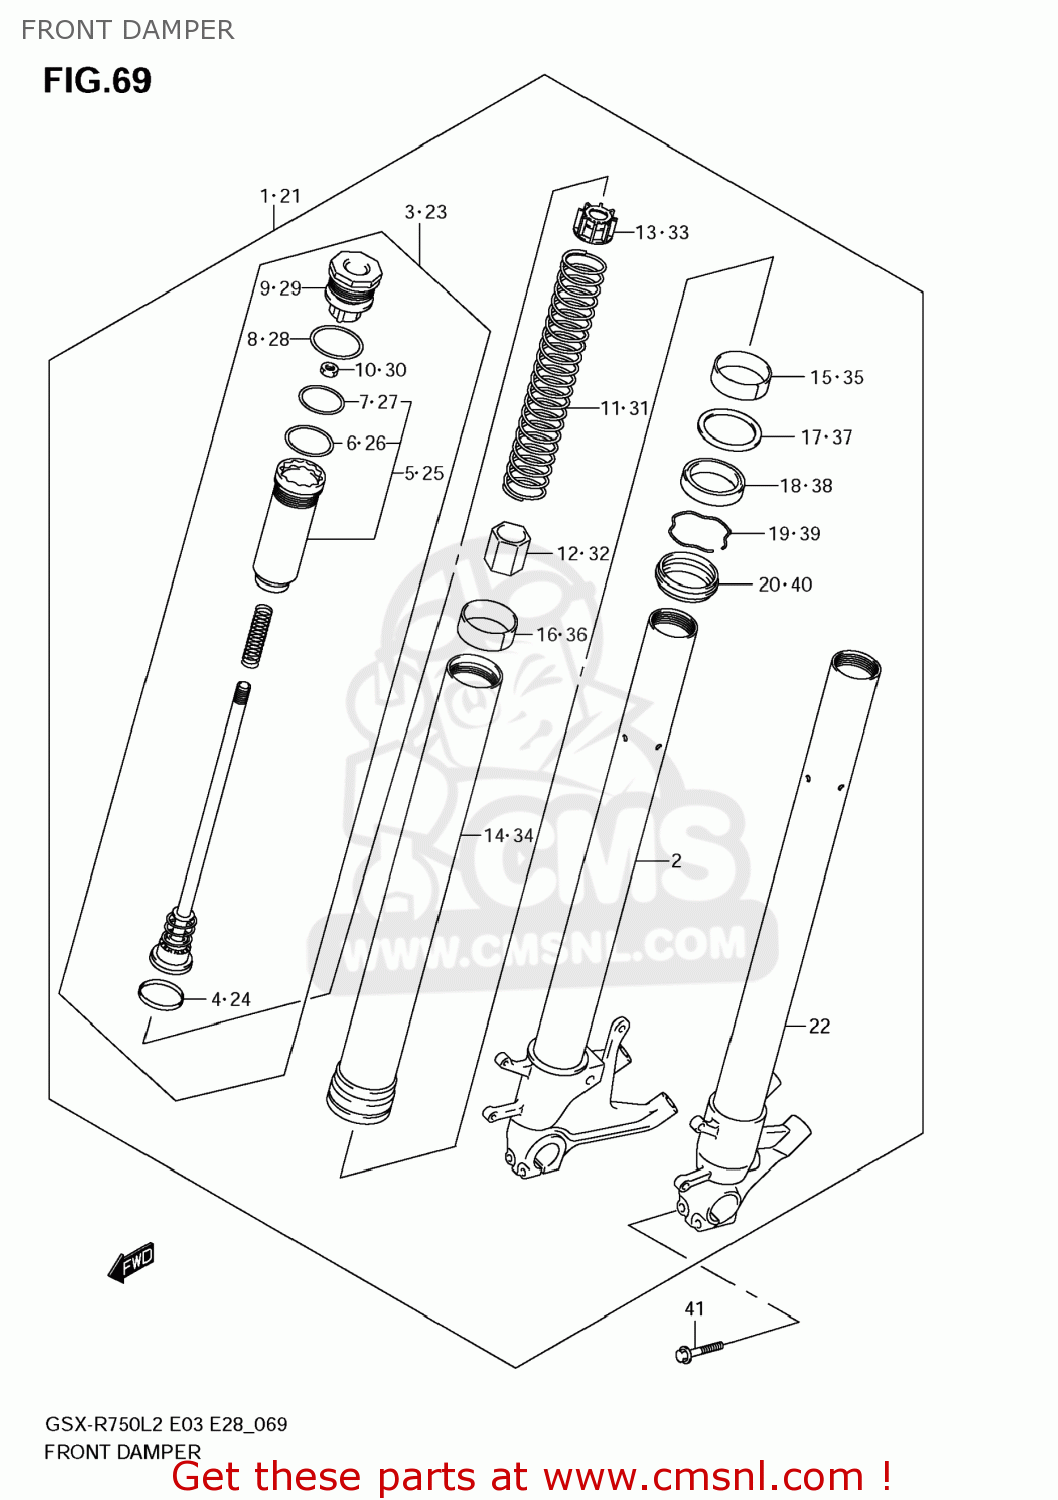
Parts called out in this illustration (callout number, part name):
1	DAMPER ASSY,FR FORK,R
2	TUBE,INNER,R
3	ROD,PISTON
4	RING,PISTON
5	CASE,ROD GUIDE
6	PISTON RING
7	O RING
8	O RING,FORK BOLT
9	BOLT
10	NUT
11	SPRING
12	COLLAR,SPRING
13	COLLAR,SPRING
14	TUBE,OUTER
15	BUSH,GUIDE
16	BUSH,SLIDE
17	SPACER,SEAL
18	SEAL,OIL
19	CIRCLIP,FORK OIL SEAL
20	SEAL,DUST
21	DAMPER ASSY,FR FORK,L
22	TUBE,INNER,L
23	ROD,PISTON
24	RING,PISTON
25	CASE,ROD GUIDE
26	PISTON RING
27	O RING
28	O RING,FORK BOLT
29	BOLT
30	NUT
31	SPRING
32	COLLAR,SPRING
33	COLLAR,SPRING
34	TUBE,OUTER
35	BUSH,GUIDE
36	BUSH,SLIDE
37	SPACER,SEAL
38	SEAL,OIL
39	CIRCLIP,FORK OIL SEAL
40	SEAL,DUST
41	BOLT
